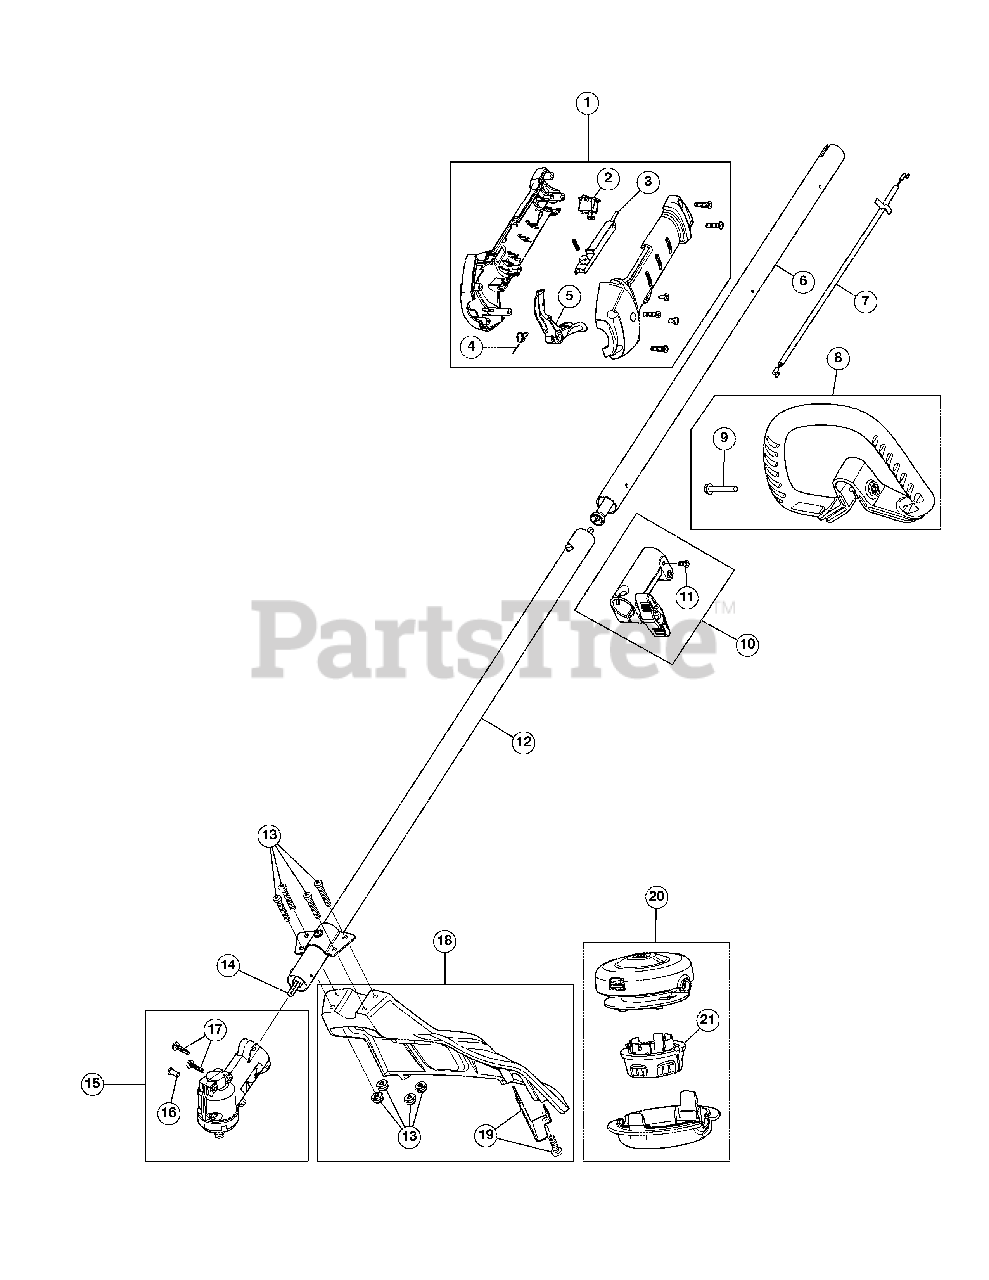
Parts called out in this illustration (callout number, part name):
1	Throttle Housing Assembly (Incl. 2 - 5)
2	Trigger Switch Assembly
3	Throttle Lock-out
4	Throttle Trigger Spring
5	Throttle Trigger
6	Upper Drive Shaft Assembly
7	Throttle Cable
8	D-Handle Assembly (Incl. 9)
10	Split Boom Coupler (Incl. 11)
11	Coupler Anti-Rotation Screw
12	Lower Drive Shaft Housing Assembly
13	Shield Mounting Screws and Nuts
14	Lower Flexible Drive Shaft
15	Gearbox Assembly (Incl. 16 - 17)
16	Gearbox Anti-Rotation Screw
17	Gearbox Mounting Hardware
18	Shield Assembly (Incl. 19)
19	Blade Assembly
20	Cutting Head Assembly (Incl. 21)
